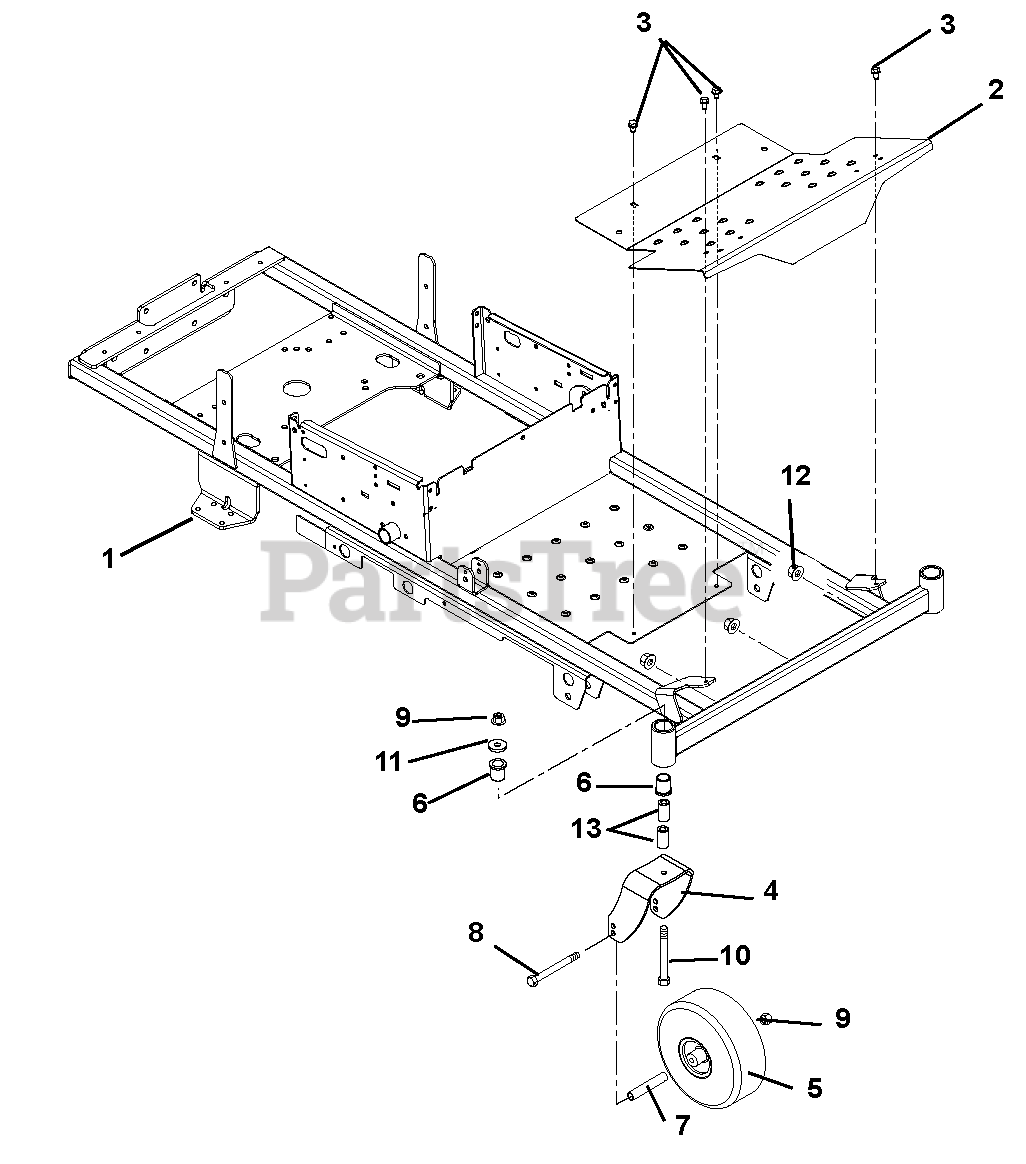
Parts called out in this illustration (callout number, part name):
1	Weldment, Frame
2	Footrest, MZ
3	Screw, Tapping .31-18 x .50
4	Fork, Caster
5	Wheel/Tire Assembly, 11.0 x 4.0 x 5.0, Monitor
6	Bushing, Flange 1.00 x 1.25 x 1.50 x 1.50
7	Spacer, Wheel
8	Bolt, Hex .50-13 x 6.50 Grade 5
9	Nut, .50-13 Nyloc Flange
10	Bolt, Hex .50-13 x 5.00 Grade 5
11	Washer, Flat Steel .511 x 1.441 x .125
12	Nut, Nyloc Flange .62-11
13	Spacer, Caster
